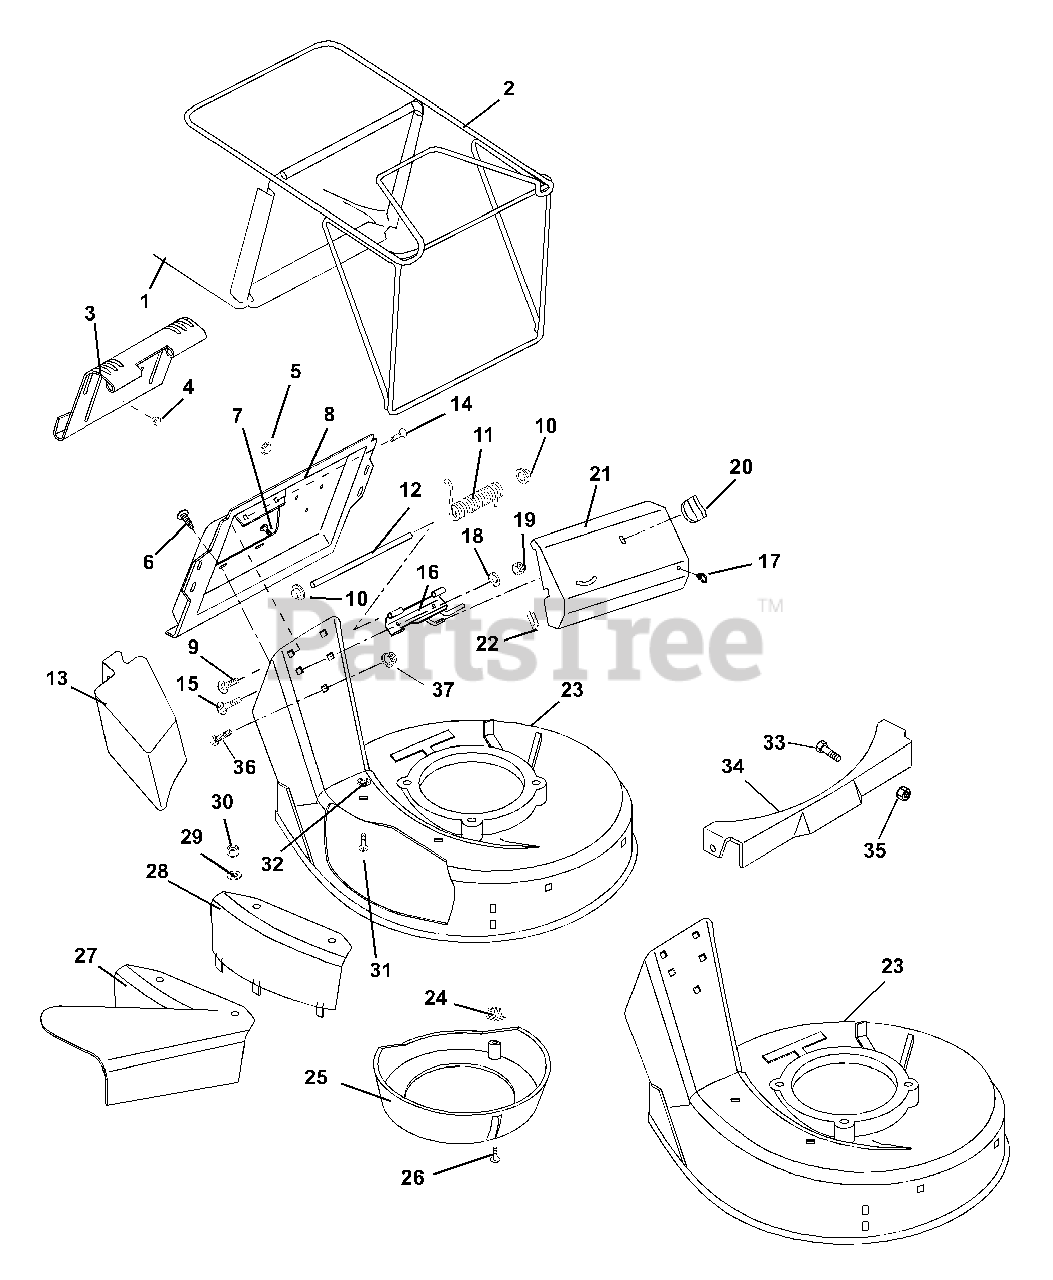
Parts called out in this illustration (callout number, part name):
1	BAG, CONSUMER BLACK 15 OZ/YD2
2	FRAME, BAGGER
3	CATCHER PLATE DOOR
4	BUTTON BUMPER
6	@SCR-TAP 12-24X.50 HWH TR YWZC
7	SCR-TAP 10-24X.375 TORX PHD YZ
8	CATCHER PLATE
8	PLATE, CATCHER
9	@BLT-RHDSSQNK .25-20X.38 G2YZ
10	PUSH NUT, .25
11	SG-TORS .120X.68X3.09
12	DOOR PIN
13	MULCH MASTER MULCHER ACCESSORY
14	@NUT-SPNLK-FLG .25-20 YWZC
15	@BLT-RDHDSQNK .25-20X.75 G5YZ
16	HINGE BASE WELDMENT
16	HINGE PLATE WELDMENT
17	SNAP-IN CLIP
18	WSHR-LK .250X.077 HVY YWZC
19	@NUT-HEX .25-20 YWZC
20	WING - NUT
21	COVER, DRIVE
22	TRIM BUMPER
23	MOWER PAN HEAD W/SFTYDECALS SP
23	MOWER PAN W/DECALS SP/COM
23	MOWER PAN W/SAFETY DECALS PUSH
24	PLASTIC GROMMET
25	CENTER BAFFLE
26	SCR-TAP 10-16X.62 SLPH AB YWZC
27	SIDE DISCHARGE ASSEMBLY
28	COVER, SIDE DISCHARGE
29	@WSHR-FL-STL.406X.812X.065 YWZ
30	@NUT-LK-NYL .312-18 YWZC
31	BLT-RDHDSQSHK.31-18X.75 GR2 YW
32	NUT-PUSH .312
33	@BLT-RDHDSQNK .31-18X.50 G5YZ
34	PANEL-FRONT
35	@NUT-LK-CTR .31-18 YWZC
35	@NUT-SPNLK-FLG .312-18 YWZC
36	@BLT-HEX .38-16X.50 GR5 YWZC
37	@NUT-SPNLK-FLG .375-16 YWZC
